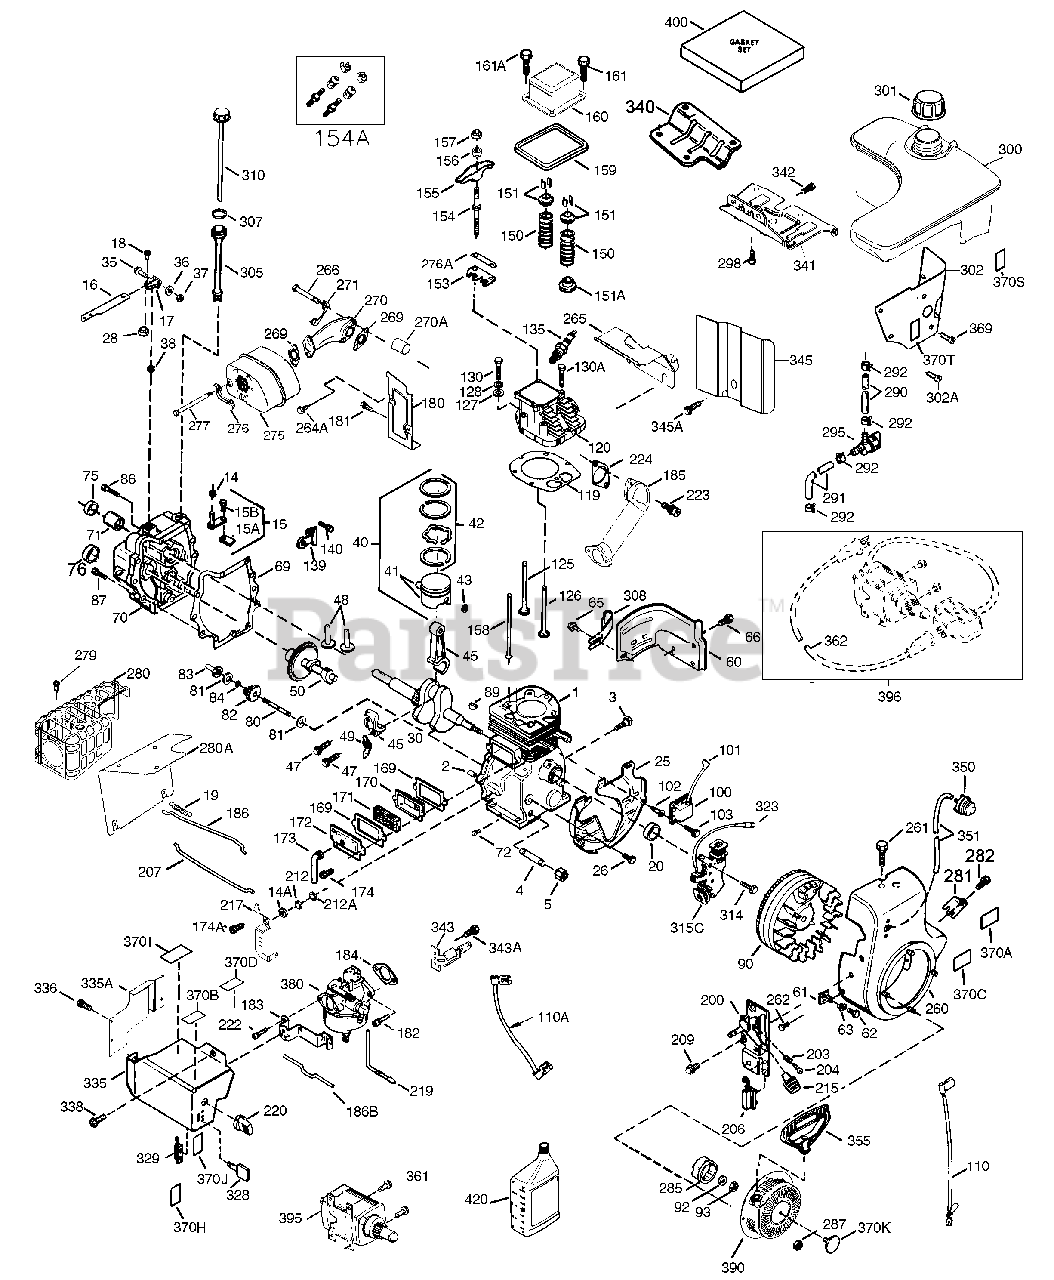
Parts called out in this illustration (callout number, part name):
1	"Cylinder (Incl. 2, 20, 72 & 72A) (3-1 /8" Bore)
2	Dowel Pin
3	Screw, 1/4-20 X 1/2" (Shoulder)
4	Oil Drain Extension (2-1/2") (1/4-18 NPT)
5	Extension Cap (1/4-18 NPT)
14	Flat Washer
15	Governor Rod (Incl. 15A & 15B)
15A	Governor Yoke
15B	Screw, 6-40 X 5/16"
16	Governor Lever Assembly (Incl. 212A)
17	Governor Lever Clamp
18	Screw, T-15, 8-32 X 7/16"
19	Governor Spring
20	Oil Seal
25	Blower Housing Baffle
26	Screw, 1/4-20 X 19/32"
28	Lock Nut, 8-32
30	Crankshaft
35	Screw, 10-32 X 3/4"
36	Lock Washer #8
37	Lock Nut, 10-32
38	Retaining Ring
40	Piston, Pin & Ring Set (Std.) (Incl. 41, 42 & 43)
40	Piston, Pin & Ring Set (.010" OS) (In cl. 41, 42 & 43)
42	Ring Set (Std.) (3-1/8")
42	Ring Set (.010" OS)
43	Piston Pin Retaining Ring
45	Connecting Rod Assembly (Incl. 47 & 4 9)
47	Connecting Rod Bolt
48	Valve Lifter
49	Oil Dipper
50	Camshaft (MCR)
60	Blower Housing Extension
65	Screw, 10-24 X 9/16"
69	Cylinder Cover Gasket
70	Cylilnder Cover (Incl. 20, 80-84)
72	Oil Drain Plug (Sq. Hd., 1/4-18)
80	Governor Shaft
82	Governor Gear Ass'y. (Incl. 81)
83	Governor Spool
84	Retaining Ring
86	Screw, 1/4-20 X 1-3/16"
87	Screw, 1/4-20 X 1- 11/16"
89	Flywheel Key
90	Flywheel (3 Amp, W/Ring Gear)
92	Belleville Washer
93	Flywheel Nut (5/8-18)
100	Solid State Ignition (Incl. 101)
101	Spark Plug Cover
102	Solid State Mounting Stud
103	Screw, T-15, 10-24 X 15/16"
110	Ground Wire
110A	Ground Wire (10.50" With Male & Femal e Flag Terminals)
119	Cylinder Head Gasket
120	Cylinder Head (Incl. 151A & 270A)
125	Exhaust Valve (Std)
125	Exhaust Valve (1/32" OS)
126	Intake Valve (Std.)
126	Intake Valve (1/32" OS)
127	Flat Washer
128	Belleville Washer
130	Screw, 5/16-18 X 2-1/2"
135	Resistor Spark Plug (Rn4C)
150	Valve Spring
151	Valve Spring Keeper
151A	Intake Valve Seal
153	Push Rod Guide
154	Rocker Arm Stud
154A	Rocker Arm Stud & Bearing Kit (Incl. 154, 156, & 157)
155	Rocker Arm
156	Rocker Arm Bearing
157	Jam Nut, 5/16-24
158	Push Rod
159	Rocker Arm Cover Gasket
160	Rocker Arm Cover
161	Screw, T-30, 1/4-20 X 1/2"
169	Valve Cover Gasket
170	Breather Body
171	Breather Element
172	Valve Cover
174	Screw, 10-24 X 1/2"
178	Nut & Lock Washer 1/4-28
180	Blower Housing Extension
183	Choke Bracket
184	Carburetor-To-Intake Pipe Gasket
185	Intake Pipe
186	Governor Link
186B	Choke Spring
200	Manual Control Bracket (Incl. 203, 20 4 & 206)
203	Compression Spring
204	Screw, T-10, 5-40 X 7/16"
206	Terminal - Shorting On-Off
207	Throttle Link
212	Bushing (Incl. 14A & 213)
212A	Bushing
213	Screw, 10-24 X 29/32"
215	Speed Control Knob
216	R.P.M. Adjusting Lever
219	Choke Rod
220	Choke Control Knob
222	Screw, 10-32 X 15/32"
223	Screw, T-30, 5/16-18 X 7/8"
224	Intake Pipe Gasket
260	Blower Housing
262	Screw, 5/16-18 X 9/16"
265	Cylinder Head Cover
266	Screw, 5/16-18 X 1-9/32" (Manifold Sh oulder Screw)
269	Exhaust Manifold Gasket
270	Exhaust Manifold
270A	Exhaust Port Liner
271	Locking Plate (Manifold)
275	Muffler (With Mounting Brackets)
276	Locking Plate
277A	Screw, 5/16-18 X 4-1/2" (Muffler Shou lder Screw)
280	Heat Shield (Must have Muffler 37264)
280B	Baffle - Air Restrictor
285	Starter Cup
290	Fuel Line (8.62" Length)
290	Fuel Line (32.0" Length)
292	Fuel Line Clamp
293A	Screw, T-30, 1/4-20 X 27-32"
295	Fuel Shut-Off Valve (Incl. 292)
298	Screw, 1/4-15 X 3/4"
300A	Fuel Tank (Incl. 292 & 301) (4-Qt.) ( Premium Style)
301	Fuel Cap (Black) (1-1/2" I.D.)
302	Fuel Tank Extension (Electric-Start P rovisions)
305	Oil Fill Tube
308	Fill Tube Clip
309	Screw, 10-32 X 5/16"
310	Dipstick
314	Screw, 1/4-20 X 3/4"
315C	Alternator Coil (18 Watt)
323	Terminal (single pin)
328	Ignition Key
329A	Screw, 8-32 X 23/64"
335	Carburetor Cover (Front)
335A	Carburetor Cover (Side)
336	Screw, 10-32 X 1/2" (Self-Drilling)
338	Screw, 10-32 X 1/2"
341	Fuel Tank Bracket (Lower) (Premium Ta nk)
342A	Screw, 5/16-18 X 7/8"
343	Key Switch Bracket (Incl. 329A)
345	Heat Baffle
350	Primer Assembly (Vented snap-in)
351A	Primer Line
355	Starter Handle (Mitten Grip)
361	Screw, T-30, 1/4-20 X 15/32"
369	Screw, 12-16 X 5/8"
370	Decal - Primer - International Symbol
370	Warning Decal
370	Decal - Tecumseh Logo For Top Of Reco il Starter
370	Decal - Push/Pull Key Information
370	Warning Decal (Bilingual)
370	Decal - Speed Control, Choke, & Key
380	Carburetor (Incl. 184)
390	Rewind Starter
396	Electric Starter Motor (120 Volt)
400	Gasket Set (Incl. Items Marked *)
420	Sae 5W30 4-Cycle Engine Oil (Quart) ( Winter)
420	0W30 Synthetic
704	Screw, 1/4-20 X 5/8"
999	Winter Maintenance Kit includes 32 oz . - SAE5W30 Oil, spark plug, switch k ey, fuel stabilizer
999	Winter Maintenance Kit includes 32 oz . - SAE0W30 Synthetic Oil, spark plug , switch key, fuel stabilizer
